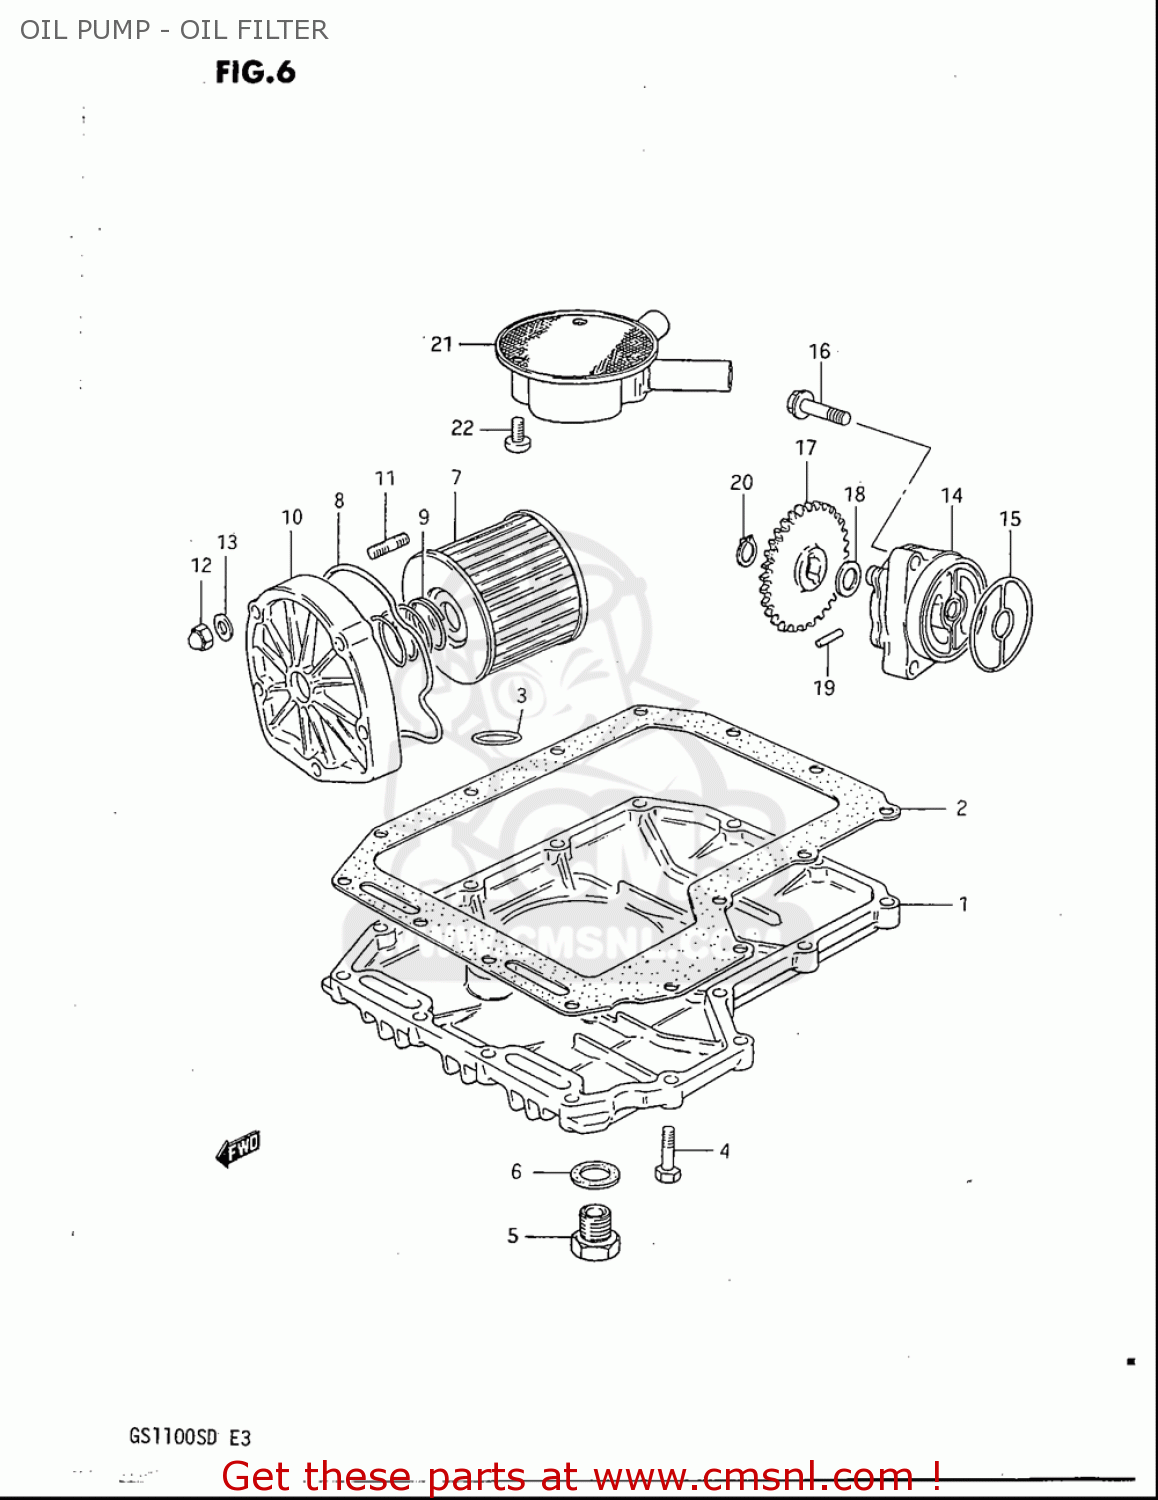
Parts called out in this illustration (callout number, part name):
1	PAN,OIL
2	GASKET,OIL PAN (NAS)
3	O RING(D:3.2,ID:12.9)
4	BOLT
5	PLUG(MAGNETO)
6	GASKET(14X19.2X2) (NAS)
7	FILTER ASSY,ENGINE OIL
8	O RING,OIL FILTER CHAMBER CAP
9	SPRING
10	CAP,ENGINE OIL FILTER
11	BOLT,STUD
12	NUT
13	WASHER
14	PUMP ASSY,ENGINE OIL
15	O RING,OIL PUMP
16	BOLT(6X32)
17	GEAR,ENG OIL PUMP DRIVEN(NT:33
18	SHIM
19	PIN(4X15.8)
20	CIRCLIP
21	STRAINER,ENGINE OIL
22	SCREW
